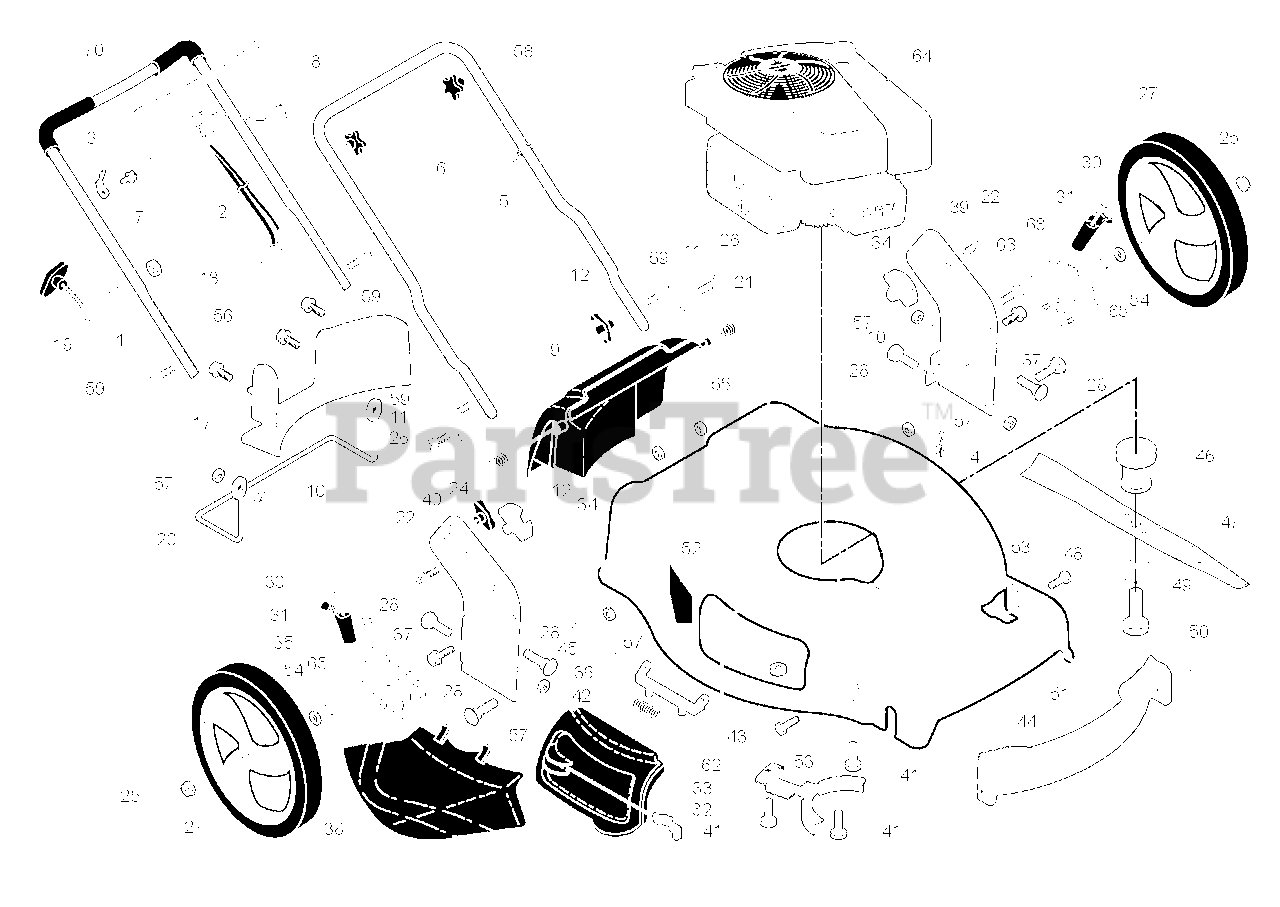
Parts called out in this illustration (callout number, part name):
2	CABLE.ASM
3	BRACKET.UPSTOP.RT
4	PUSH CLIP
5	TIE GUIDE
6	KNOB.HANDLE.PLASTIC.STAR.BLACK
11	COTTER.HAIRPIN.DOOR/HANDLE.PIV
12	KNOB, DEFLECTOR
18	NUT
19	GUIDE.ROPE.STD.BLK.ZIN
21	SPRING.LH.GRAY
22	SCREW.PAN.HEAD.#10
24	SPRING.RH.GRAY
25	NUT.HEX.FLANGE.3/8-16.LOCKNUT
26	SCREW,DOOR/HANDLE.PIVOT
28	BOLT
36	HINGE BRACKET ASSEMBLY
37	BOLT.HEX.HD.WASHER.5/16-18X.75
38	DEFLECTOR.CLIPPING.22.BLACK
41	BOLT 3/8-16X1-1/8
42	SPRING.TORSION
43	NUT.HEX.FLANGE.1/4
45	ROD.HINGE.21
46	ADPTER.BLAD.25M.VS.22PLU.STAR
48	WASHER,HARDEN
49	LOCKWASHER
50	SCREW, HEX HD 3/8-24 X 1-3/8
52	DANGER DECAL
53	BOLT.5/16HEX.WHS.HD
54	WASHER PM
55	NUT.HEX.FLANGE.1/4
56	SCREW.HX.13X.750
57	NUT.FLANGE.5/16
59	BOLT, HANDLE 5/16-18X1.75
62	BELT KEEPER
65	O-RING..070X.487.NEOPRENE
70	GRIP.HANDLE.FOAM.WIDE.(1 SIDE)
